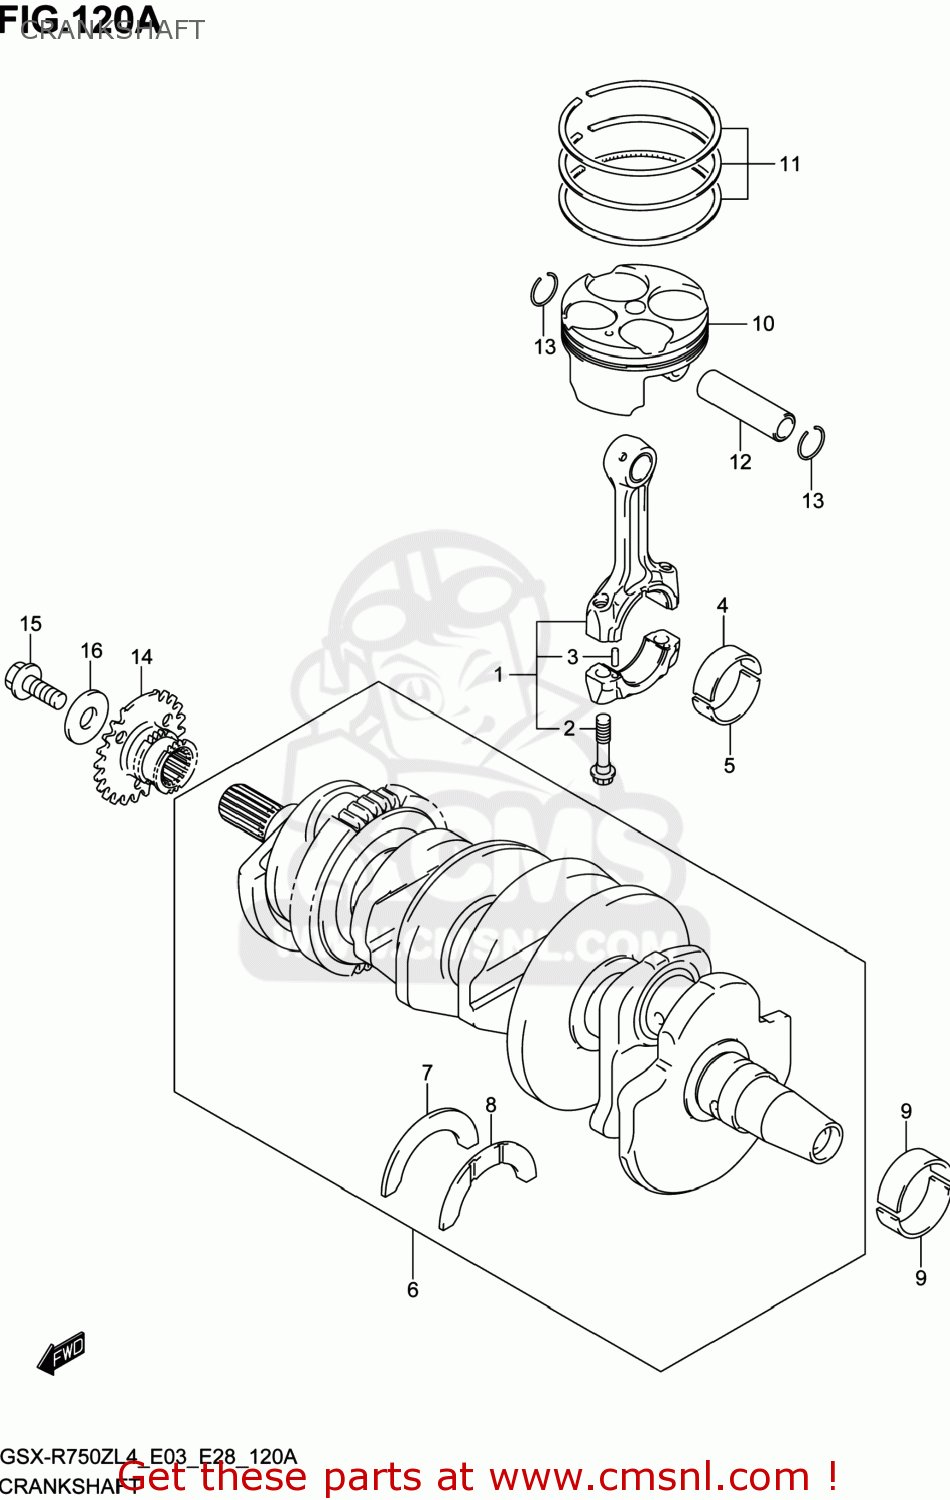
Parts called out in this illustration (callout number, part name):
1	CONNECTING ROD ASSY
2	BOLT,CONNECTING ROD
3	PIN
4	BEARING,CRANK PIN
5	BEARING,CRANK PIN GREEN
6	CRANKSHAFT SET
7	BEARING,CRANK THRUST(GREEN)
8	BEARING,CRANK THRUST(RED)
9	BEARING,CRANKSHAFT
10	PISTON
11	RING SET,PISTON
12	PIN,PISTON
13	CIRCLIP
14	SPROCKET,CAM CHAIN DRIVE
15	BOLT(10X23)
16	WASHER
